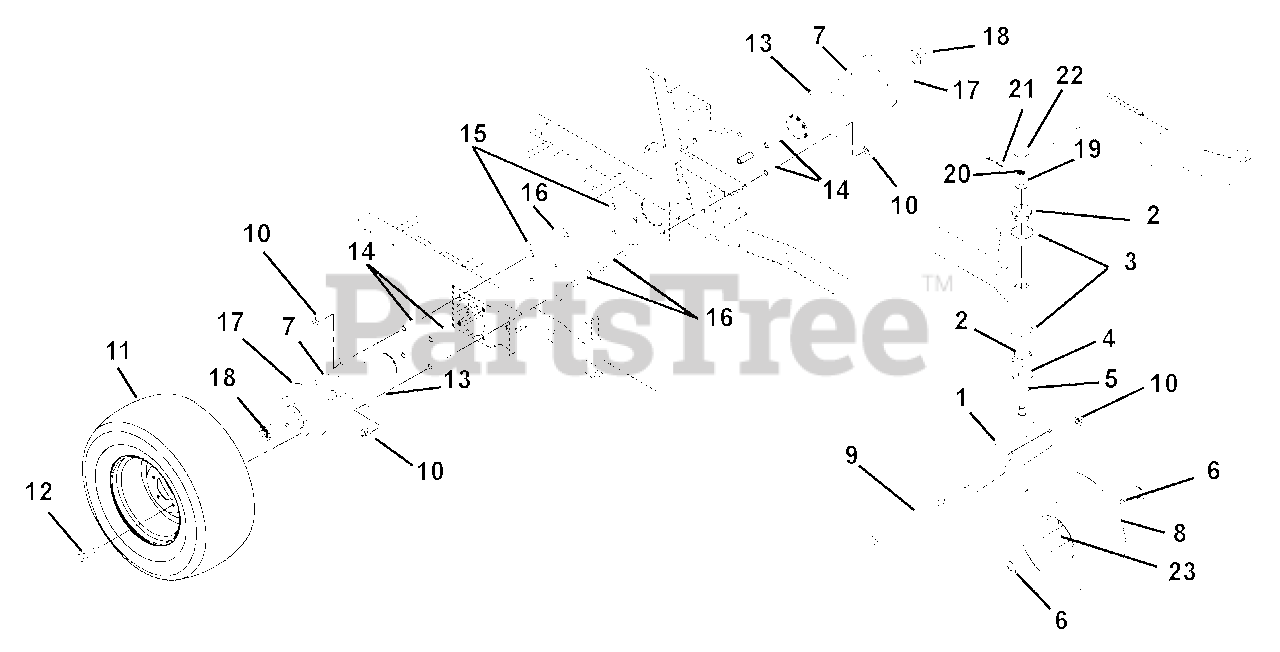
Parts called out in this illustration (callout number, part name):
1	FORK - BLACK
2	BRG, CONE W/ GREASE
3	BRG-CUP1.980X.420
4	BEARING SEAL 1.5 X 2 X .18
5	SPACER 1.005X1.5075X.375
6	SPACER, WHEEL
7	KEY-WDRF .31X1.00 SFT #B
8	WHEEL/TIRE ASM
9	@BLT-HEX .50-13X9.00 GR5 YWZC
10	@NUT-LK-TOP-FLG .50-13 YWZC
11	WHL/TIRE 23X9.50-12 MULTITRAC
12	BLT, LUG .50-20 X 1.38
13	WHEEL MOTOR, MB15
14	BSHG-SLV .513X.748X2.129
15	PLATE, MOTOR SUPPORT
16	BOLT, WHEEL MOTOR 1/2-13X5.00
17	HUB & DISK (PARK) 8" 1/2 HOLE
18	NUT-LK-JAM-PTCH 1.00-20
19	WSHR-FL-STL.755X1.375X.062YWZC
20	NUT, SLOTTED .75-16
21	@PIN-CTR .16X1.00 EXTPRSQCT YZ
22	CAP,DUST
23	BRG, 25MM ID X 52MM OD X 15MM
